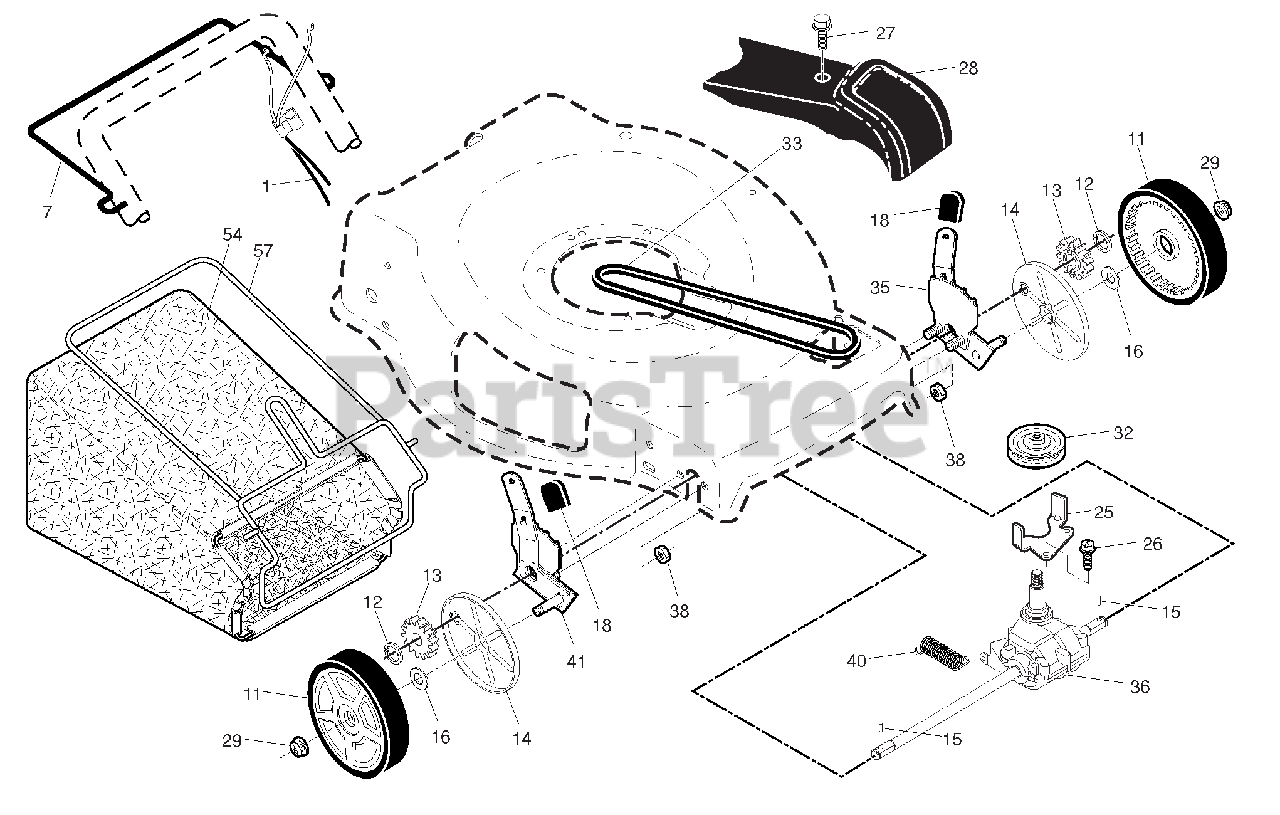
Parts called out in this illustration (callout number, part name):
1	CABLE, DRIVE CONTROL
7	CONTROL BAR, DRIVE
11	WHEEL & TIRE ASSEMBLY
14	DUST COVER
15	Pawl, Drive
16	Washer, Flat 3/8
18	Selector Knob
25	BELT KEEPER
26	SCREW, HI-LO THREAD #12 X 5/8
27	Pan Head Tapping Screw #10-24
28	DRIVE COVER
29	Nut, Hex
32	DRIVE PULLEY
35	KIT WHEEL ADJUSTOR FRONT LH
36	GEARCASE ASSEMBLY, COMPLETE
38	LOCKNUT, HEX 1/4-20
41	KIT WHEEL ADJUSTOR FRONT RH
54	GRASSBAG
57	FRAME, GRASSBAG
